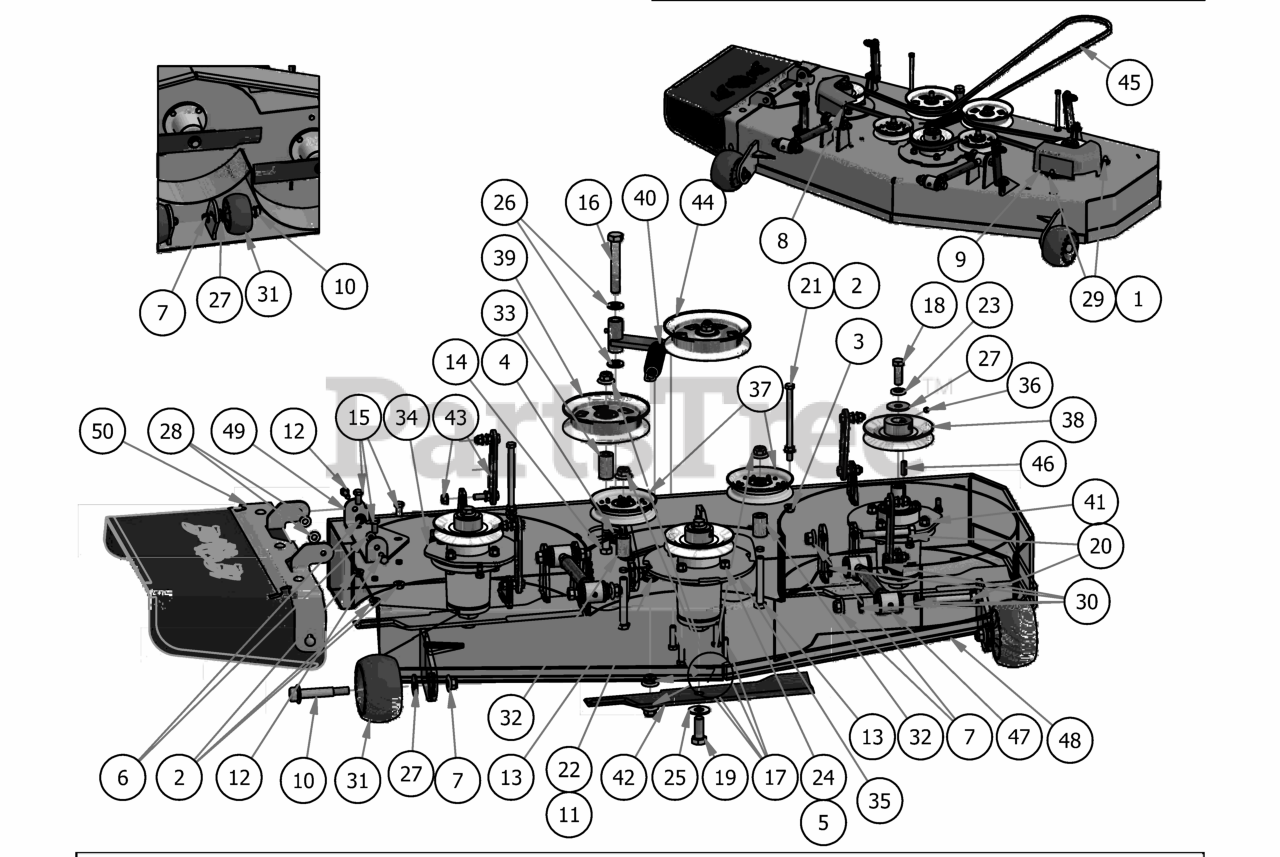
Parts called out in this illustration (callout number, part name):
1	Acorn nut-pulley Cover
2	3/8" Flange Nut
3	3/8" Nylock Flange Nut
4	5/8-11 Nylon Insert Jam Half Nut
5	3/8" Hex Nut
6	5/16" Nylon Flange Nut
7	1/2-13 Nylon Flange Nut
8	pulley cover chute side
9	pulley cover non-chute side
10	Deck Wheel Bolt
11	1/2 x 2" Carriage Bolt
12	5/16-18 x 1 GR 5 Hex Bolt Zinc
13	1/2 x 3 1/2 Flange Bolt Grade 8
14	1/2" x 4" Bolt (Grade 8)
15	3/8" x 3/4" Hex Bolt
16	5/8" x 4" Hex Bolt
17	3/8 x 1.5" Bolt
18	1/2"-20 x 1 1/2 - Grade 5 Fine Thread Bolt
19	5/8 x 1 1/2 Grade 8 Hex Bolt (Fine)
20	1/2-13 x 3 1/2 GR 5 Hex Bolt
21	3/8-16 x 5 1/2 Hex Bolt
22	.517 Square Hole Round Washer
23	1/2" Lock Washer Zinc
24	3/8" Lock Washer
25	5/8'' Flat Washer
26	.630 ID Plastic Washer
27	1/2" Belleville Washer
28	.360 ID Plastic Washer
29	.360 ID Plastic Washer-Black
30	.505 Nylon Spacer
31	Deck Wheel
32	.502 ID X .750 OD X 1.500 Long Spacer
33	1 3/4" Pulley Spacer
34	42&48 Deck Spindle Support Plate
35	Deck Spindle Support Plate
36	5/16 Set Screw
37	4 3/4 Idler Pulley - ABFI-76
38	5" Spindle Deck Pulley
39	5-3/4 Idler Pulley
40	Deck Idler Spring
41	Spindle Assembly
42	16 1/4" Bad Boy Blade
43	Deck Hanger Assembly
44	2017 54"/48" Deck Idler Assembly
45	B147 Deck Belt
46	1/4" x 1" Key
47	2018 Maverick Turnbuckle (Top Link)
48	2017 48" ZT Deck
49	Discharge Chute Hanger (deck mounted)
50	ZT Chute Assembly
